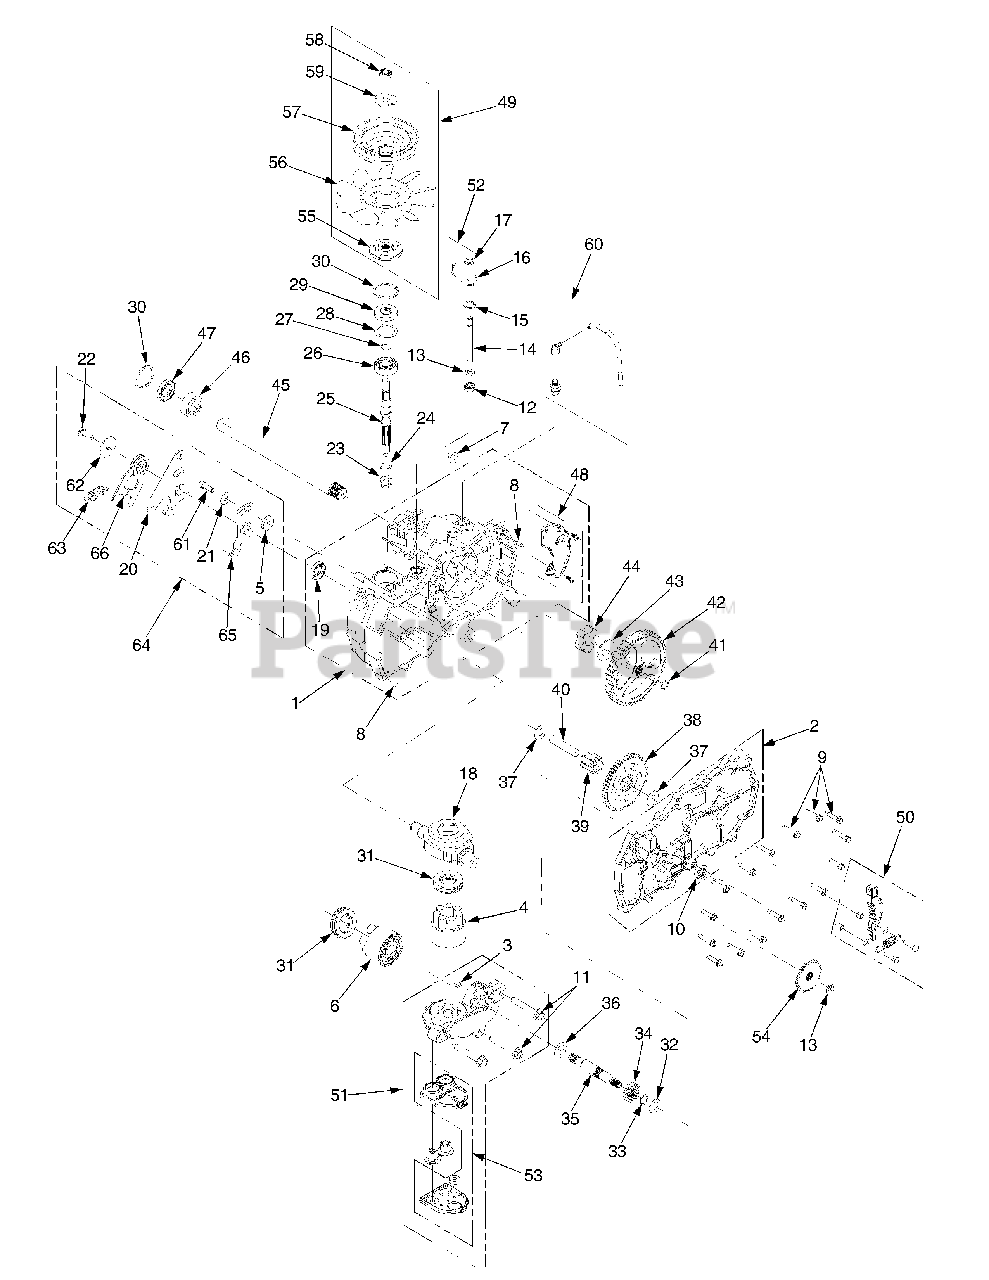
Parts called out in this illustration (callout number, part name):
1	Housing Ass’y, Main RH
2	Side Ass’y RH
3	Plate, Bypass
4	Block Kit - 7 Piston
5	Spacer, .32 x 1.005 x .179
6	Block Assembly, Cylinder
7	Straight Thread Pipe
8	Std. Handle Pin
9	Hex Flange Screw
10	Oil Seal .625 x 1.0 x .25
11	Screw
12	Seal, Lip
13	Retaining Ring .375 Ext.
14	Rod, Bypass
15	Retaining Ring .75 Int.
16	Arm, Bypass
17	Retaining Ring
18	Swashplate, trunnion
19	Seal, Lip
20	Control Arm RH
21	Washer 7/16 x 7/8 x .060
22	Screw, 5/16-24 x 1.0
23	Block Washer
24	Block Thrust Washer
25	Input Shaft
26	Ball Bearing
27	Retaining Ring
28	Spacer
29	Lip Seal
30	Retaining Ring
31	Thrust Washer
32	Flat Washer 5/8 x 1.0 x .05
33	Retaining Ring
34	Gear, Pinion, 13T
35	Shaft, Motor
36	Motor Shaft Washer
37	Washer, HT
38	Gear, 10T/48T
39	Gear, 10T Jackshaft
40	Pin, Jackshaft
41	Retaining Ring
42	Gear, Bull, 52T
43	Washer, 1.018 x 1.57 x .105
44	Sleeve Bearing
45	Shaft, Axle, 1.0 x 11.7
46	Bearing, Sleeve
47	Seal, Lip
48	Plate Kit, Expansion RH
49	Kit, Fan Pulley
50	Kit, Brake Arm
51	Kit, Center Section RH
52	Kit, Bypass Arm RH
53	Filter Assembly
54	Disc, Brake Cog
55	Hub, Pulley
56	Fan, 7" 10 Blade
57	Pulley, 4.5
58	Hex Ins. L-Nut 1/2-20
58	Seal Kit
58	Sealant
59	OD Slotted Washer
60	Breather Kit
61	Screw, Patch 5/16-24 x 1
62	Washer, .343 x 1.5 x .062
63	Extension Spring
64	Kit, Return Assembly RH
65	Arm, Neutral
66	Scissors Arm Kit
